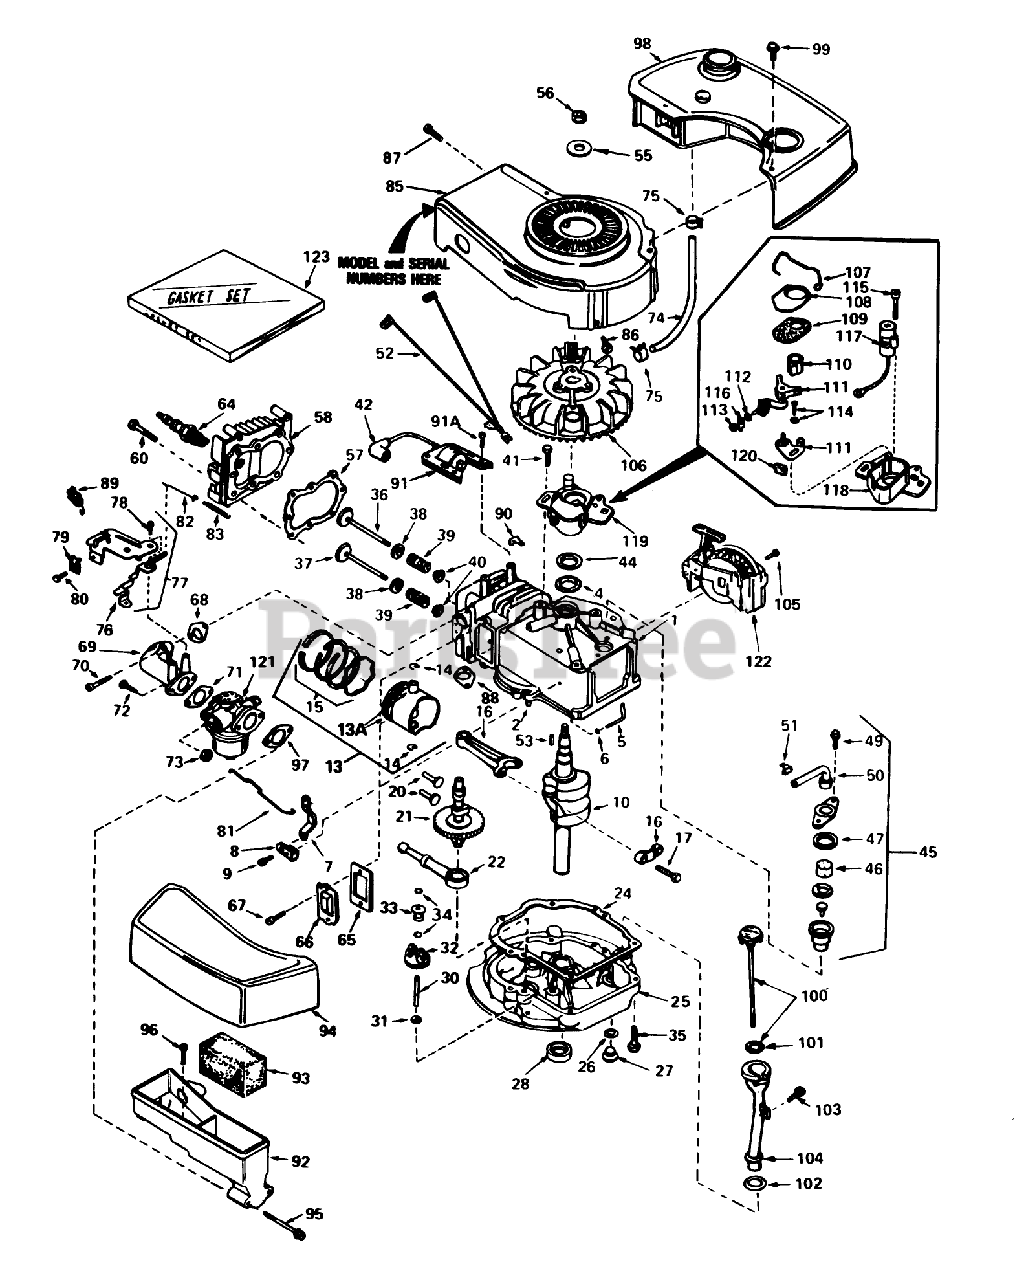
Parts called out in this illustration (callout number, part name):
1	Cyiinder Assy. (Incl. Ref. #2, 4 105)
2	Pin-Dowel
4	Seal-Oil
5	Rod, Governor (Incl. No. 36)
6	Washer-Flat
7	Governor Lever
8	Clamp-Lever, Governor
9	Screw
10	Crankshaft
13	Piston, Pin Ring Assy. (Std.) (Incl. Ref. #13A, 14 15)
13	Piston, Pin Ring Assy. (.010 oversize) (Incl. Ref. #13A, 14 15)
13	Piston, Pin Ring Assy. (.020 oversize) (Incl. Ref. #13A, 14 15)
13A	Piston Pin Assy. (Incl . Ref. . #14) (Std.)
13A	Piston Pin Assy. (Incl. Ref. #14) (.010 Oversize)
13A	Piston Pin Assy. (.020 oversize) (Incl. Ref. #14)
14	Ring-Retaining, Piston Pin
15	Ring Set (Std.)
15	Ring Set (.020" OS)
15	Ring Set (.010" OS)
16	Rod Assy., Connecting (Incl. Ref. #17)
17	Bolt-Rod, Connecting
20	Lifter-Valve
21	Camshaft(Mech.Comp. Release)
22	Oil Pump ASM
24	Gasket, Mounting
25	Flange Assy., Mounting (Incl. Ref. #26thru 30)
26	Gasket-Oil Drain
27	Plug Oil Drain
28	Seal Oil
30	Shaft-Governor
31	Washer-Flat
32	Governor Gear ASM
33	Spool-Governor
34	Ring-Retaining
35	Screw (1/4-20 x 1-1/4)
36	Valve, Intake (Std.) (Incl. Ref. #40)
36	Valve, Intake (1/32" oversize)(Incl. No. 40)
37	Valve, Exhaust (Std.)(Incl. No. 40)
37	Valve, Intake (1/32" oversize)(Incl. No. 40)
38	Cap-Upper Valve Spring
39	Spring-Valve
40	Cap-Valve, Spring
41	Screw
42	Cover-Spark Plug
44	Gasket Stator
45	Breather Assy. (Incl. Ref. #46 thru 51)
46	Element-Breather
47	Gasket-Breather
49	Screw (10-24 x 9/16)
50	Tube, Breaker
51	Clip, Breather
52	Wire Ground
53	682488 LB GRASS HI-
55	Washer-Belleville
56	Nut-Flywheel
57	63573 GIL 42 SNWTHW
58	Head-Cylinder
60	Screw (5/16-18x1-1/2)
64	Plug, Spark (J17LM or equiv.)
64	Plug, Spark (Champion RCJ-8)
65	Gasket-Breather
66	Cover-Valve
67	Screw
68	Gasket-Intake
69	Pipe, Intake (Incl. No. 68)
70	Screw (1/4-20 x 1)
71	Gasket-Carburetor
73	Nut and Lock Washer (1/4-28)
74	Line-Fuel
75	Clamp-Line, Fuel
76	Lever Control
77	Control Assy., Speed (Incl. Nos, 76, 78 89)
78	Screw, Hex Washer Hd Shoulder Self-Tap
79	Conduit
80	Screw (10-32 x 3/8)
81	Link-Throttle
82	Link Governor Spring
83	Spring Governor
85	Housing Blower
86	Screw
87	Screw (10-24 x 9/16)
88	Gasket Exhaust
89	Terminal
90	Clip-Wire
91	Lamination Coil Assy. (Incl. No. 42)
91A	Screw
92	Body Air Cleaner
93	Filer, Air
94	Cove, Air Cleaner
95	Screw Fil Hd.
96	Screw, Hex Hd.
97	Gasket-Air Cleaner
98	Tank, Fuel
99	Screw (10-32 x 35/64)
100	Dipstick, Oil (Incl. Ref. #101)(Twist Lock)
101	O-Ring
102	Gasket
103	Screw (10-32 x 1/2)
104	Tube-Oil Fill
105	Screw (1/2-20x5/8)
106	FIywheel
107	Spring Breaker Box
108	Cover-Dust
109	Gasket-Dust Cover
110	Cam-Breaker
111	Breaker Assy.
112	Washer
113	DECAL
114	Breaker Screw
115	Condenser Screw
116	Terminal, Ground
117	Condenser
118	Stator Plate
119	Stator Plate Assy. (incl. Nos. 107, 111 thru 118 120)
120	Felt,Cam Wiper
121	Carburetor (Incl. Ref. #71)
122	Starter-Sidemount
123	Gasket Set
